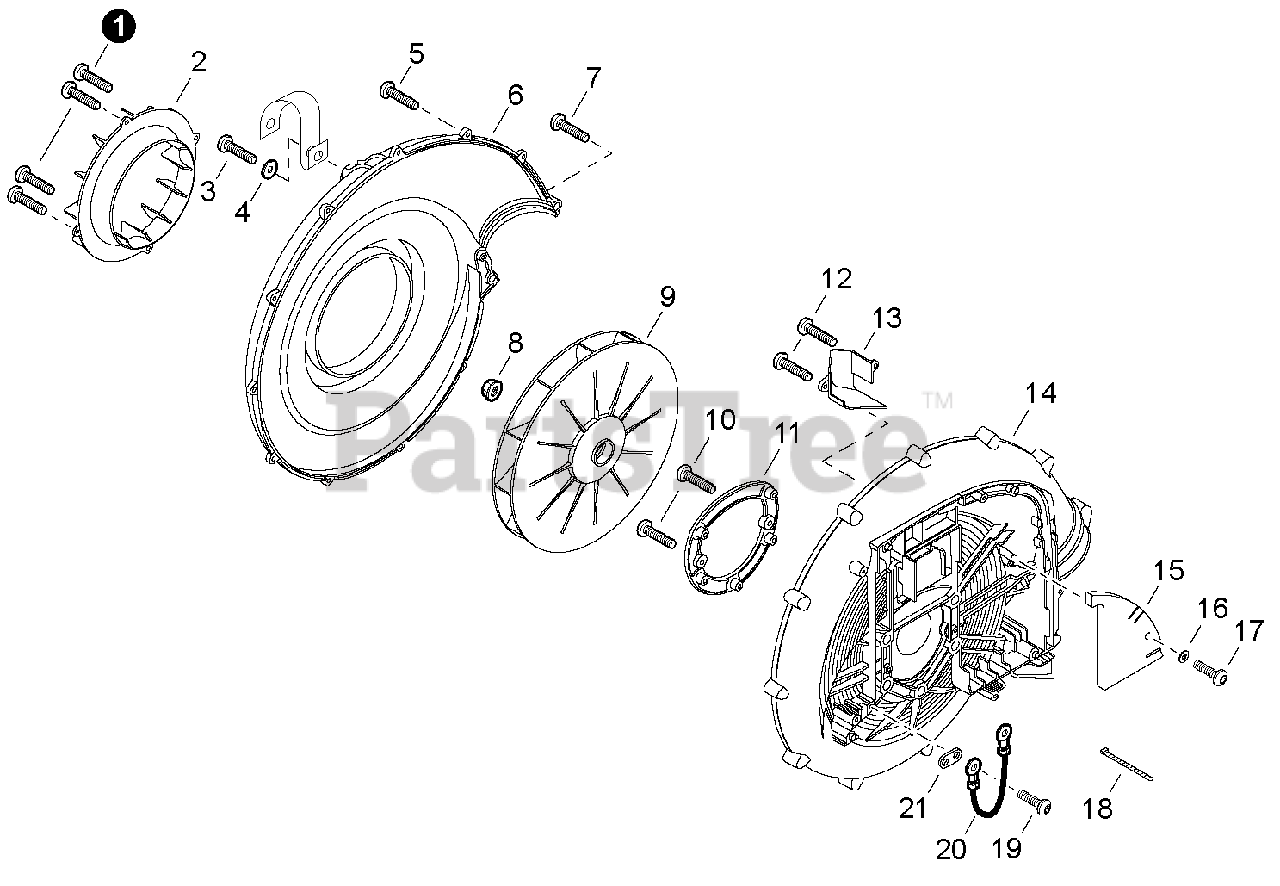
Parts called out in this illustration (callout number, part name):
1	SCREW - 5X16
2	DEFLECTOR, AIR
3	SCREW - 5X20
4	WASHER - 5
5	SCREW - 5X20
6	COVER, FAN - INNER
7	SCREW - 5X20
8	NUT - 10 -- FLANGE
9	FAN
10	SCREW - 5X16
11	PLATE, ENGINE
12	SCREW - 5X16
13	GUIDE, AIR
14	COVER, FAN - OUTER
15	PAD, FOAM
16	WASHER - 5
17	SCREW - 5X16
18	TIE, CABLE - SMALL
19	SCREW - 5X16
20	LEAD - GROUND
